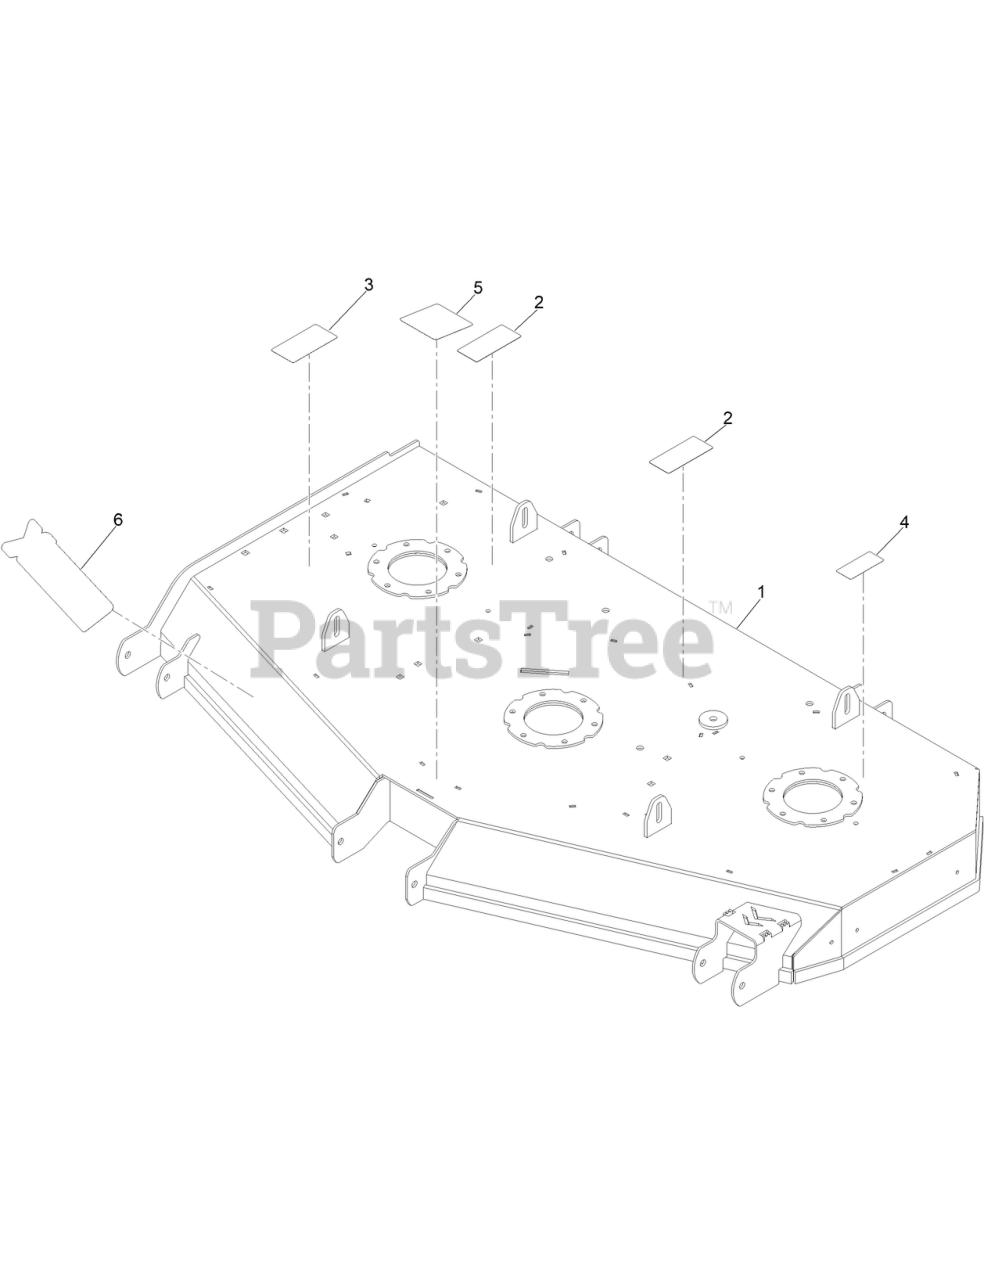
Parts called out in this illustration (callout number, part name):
2	DECAL-ROTATING FAN HAZARD
3	DECAL-DANGER, DECK
4	DECAL-SAFETY BLADE TORQUE
5	DECAL-DECK BELT ROUTING
6	DECAL-DECK, 60
